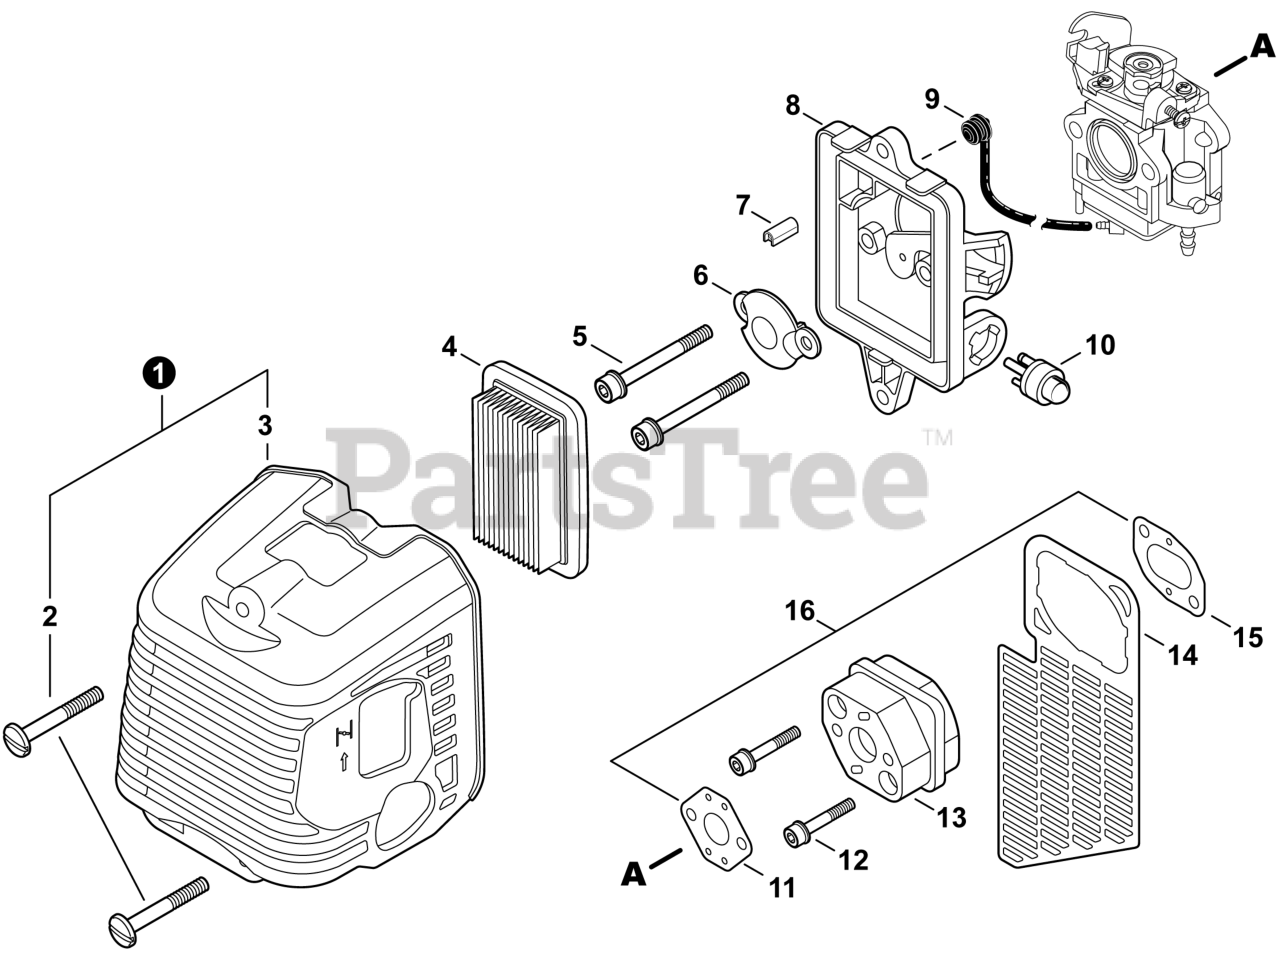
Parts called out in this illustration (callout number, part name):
1	COVER ASSY, AIR FILTER
2	SCREW 5x20
3	COVER, AIR FILTER
4	FILTER, AIR
5	BOLT 5x55
6	PLATE, PREVENT
7	PIPE, INTAKE
8	CASE, AIR FILTER
9	GROMMET, W/VENT PIPE 3x6x105
10	BULB, PURGE
11	GASKET, INTAKE
12	BOLT 5x25
13	INSULATOR, INTAKE
14	SHIELD, DEBRIS
15	GASKET, INTAKE
16	GASKET KIT
